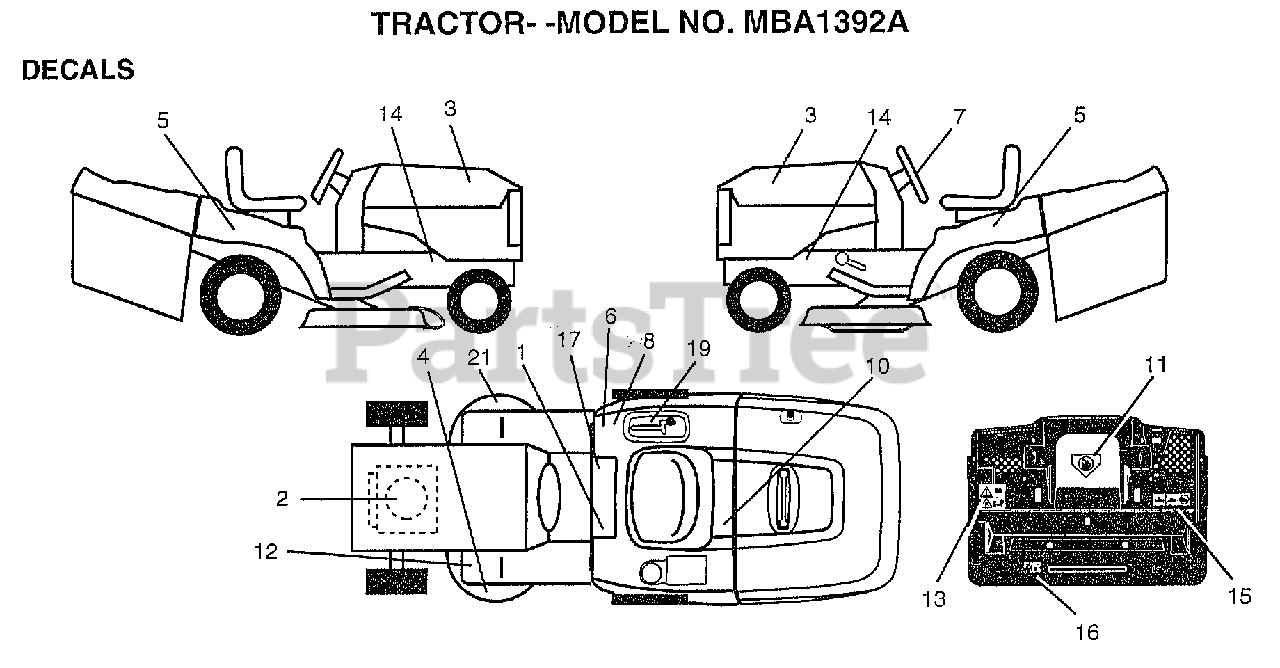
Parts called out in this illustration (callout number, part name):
1	DECAL.READ.O.MANU
2	DECAL HP ENGINE
3	DECAL, NAMEPLATES
4	"DECAL,ENVIRO DECK"
5	DECAL.FEND.13/92.6SP
7	DECAL.WHL.STEERING
8	DECAL.EURO.ST.CE.
10	DECAL.BATRY.3-3908
11	DECAL.DANGER.CUTF
12	DECAL-BRAKE/CLUTC
13	DECAL.WARNING.BACKPLATE.CRD
14	"DECAL CHASSIS,HOT"
15	DECAL, OPER BAG
16	DECAL.DRAWBAR.LDL
17	DECAL BRAK PARK
19	DECAL.CONSOLE.6SP.CRD
21	DECAL.DECK.HEX.BELT
